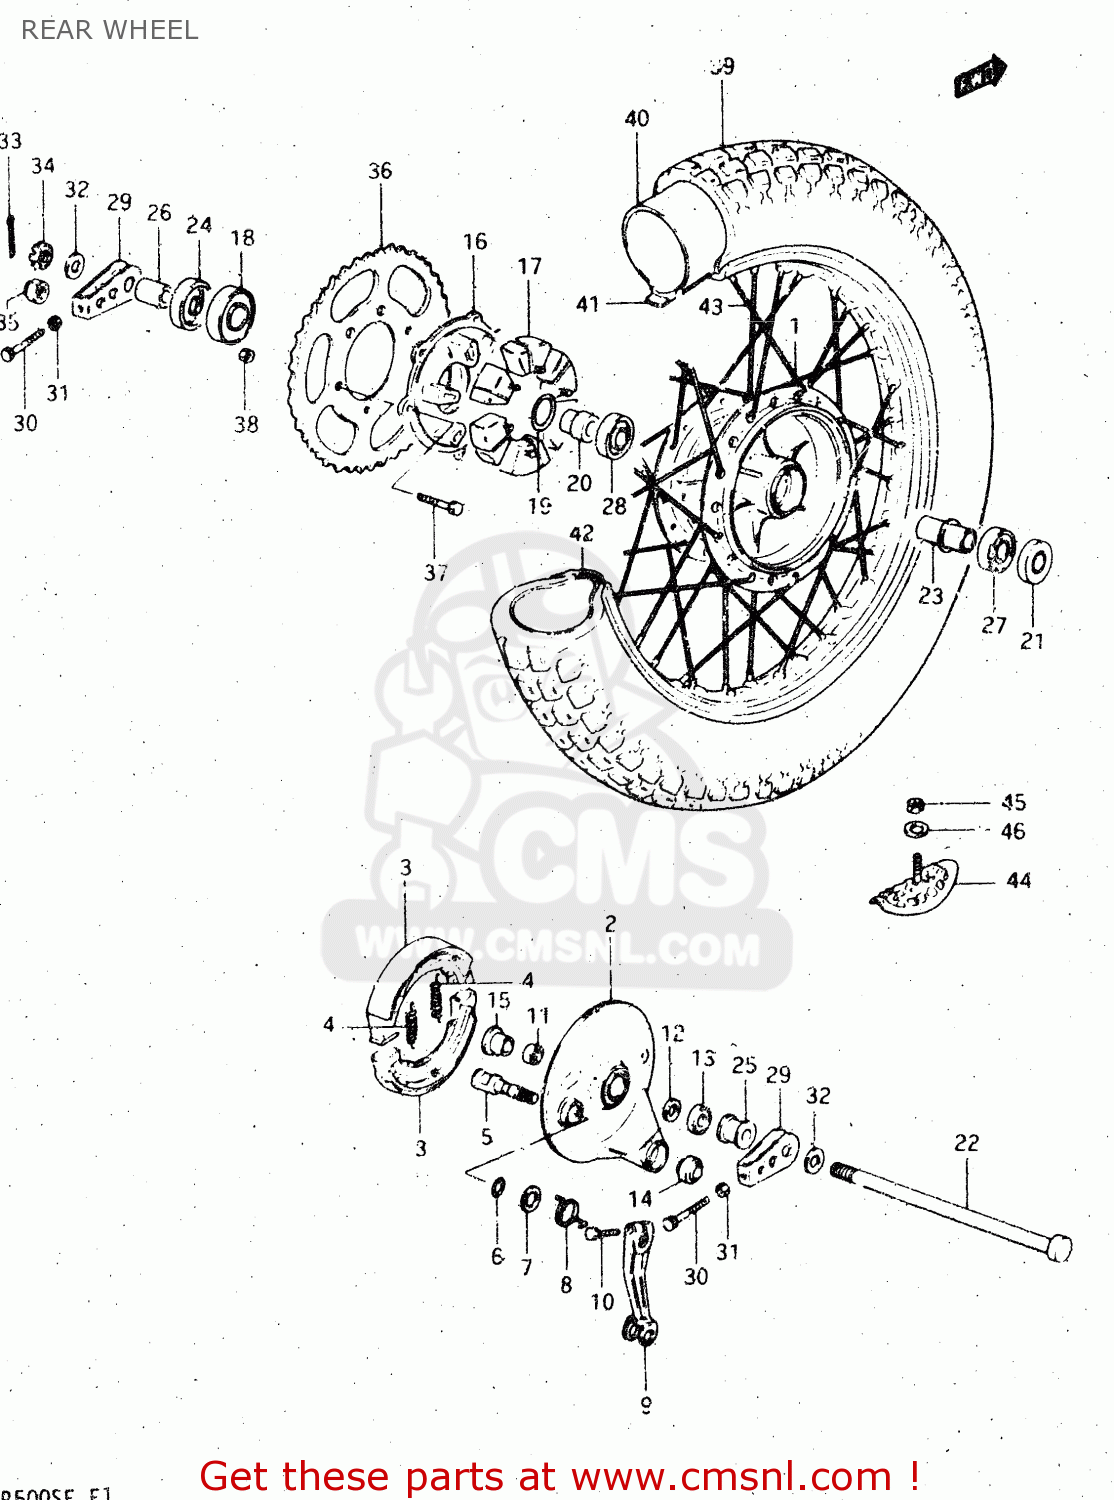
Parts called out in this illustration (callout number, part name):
1	DRUM,REAR HUB
2	PANEL,REAR HUB
3	SHOE,BRAKE (MCA)
4	SPRING
5	CAM,FRONT BRAKE
6	O-RING,BOSS
7	WASHER (15X24X1.6)
8	SPRING
9	LEVER,REAR BRAKE CAM
10	BOLT
11	BEARING(24X31X28)
12	WASHER
13	CVR,RR BRAKE AHR PNL DUST SEAL
14	SPHERICAL BRNG,TORQUE LINK
15	SPACER,REAR HUB PANEL
16	DRUM,REAR SPROCKET MOUNT
17	ABSORBER,RR HUB SHOCK
18	BEARING
19	O-RING
20	SPACER,REAR SPROCKET DRUM
21	OIL SEAL
22	AXLE,REAR
23	SPACER,REAR HUB BEARING
24	SEAL,OIL(30.5X52X8)
25	SPACER,REAR AXLE,RIGHT
26	SPACER(17X30.5X16.3)
27	BEARING
28	BEARING
29	ADJUSTER,CHAIN
30	BOLT
31	NUT
32	WASHER (17X30X3.2)
33	PIN,COTTER
34	NUT
35	NUT
36	SPROCKET,RR(NT:45)
37	BOLT
38	NUT
39	TIRE
40	TUBE,INNER
41	PROTECTOR,WHEEL,INNER
42	RIM,REAR WHEEL
43	SPOKE ASSY,RR WHEEL
44	STOPPER,BEAD
45	NUT
46	WASHER
